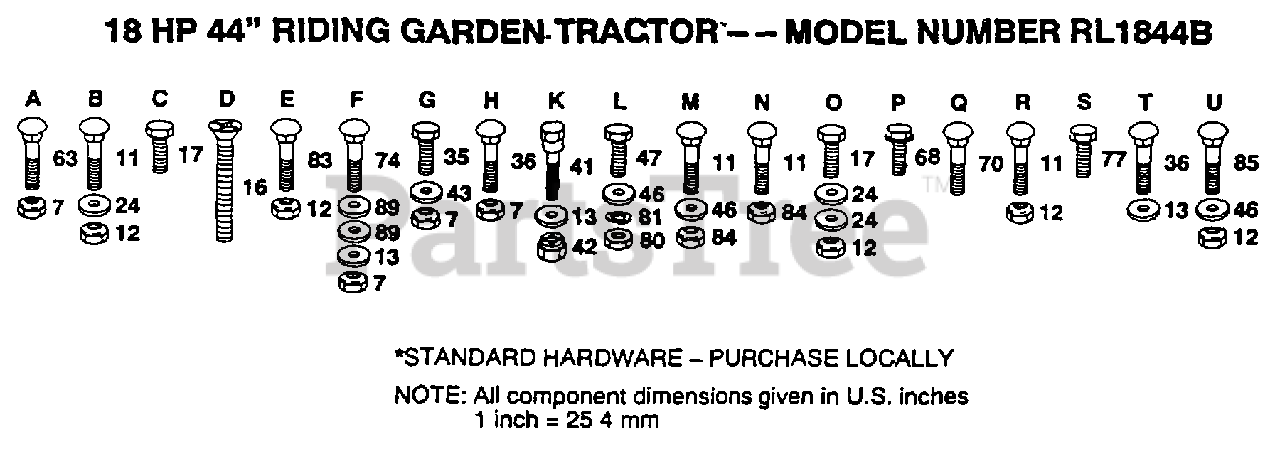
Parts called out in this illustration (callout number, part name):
11	BOLT
13	WASHER
16	SCREW YT
24	WASHER M
35	BOLT - HEX 3/8 - 16 X 3
41	BOLT SHOULDER
42	LOCKNUT
43	WASHER
46	WASHER
63	BOLT
68	SCREW
70	BOLT
74	BOLT
77	BOLT
80	NUT.HEX.5/16-18
81	LOCKWASHER
83	BOLT
89	WASHER
